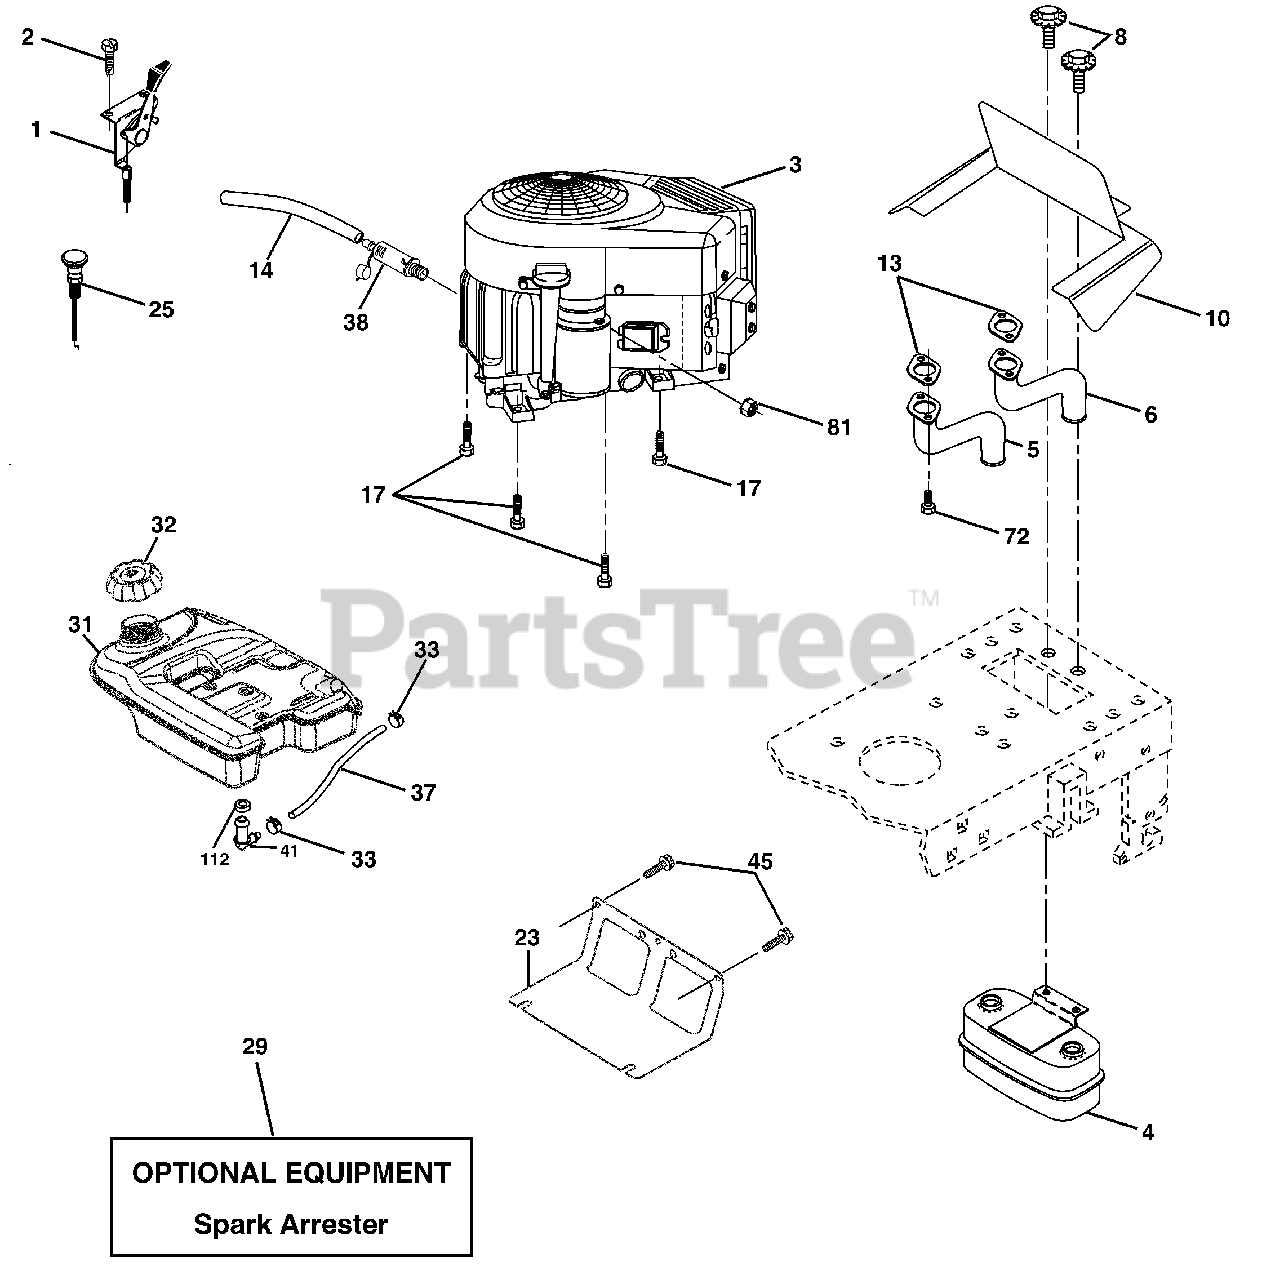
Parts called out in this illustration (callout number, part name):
1	Control Throttle
2	Screw Hw Hd Hi-Lo #13-16 x 3/4
4	Muffler Asm Twin Lo-Tone
5	Pipe Exhaust LH Intek
6	Pipe Exhaust RH Intek
8	Bolt 5/16-18 unc x 3/4 w/Sems
10	Shield Browning Intek II
13	Muffler Gasket
14	Tube Drain Oil Easy
17	Screw Thdrol 3/8-16 x 1-1/2
23	Shield Heat
25	Choke Control
29	Kit Spark Arrestor (Flat Scrn)
31	Tank Fuel 4.0 Rear
32	Cap Asm Fuel
33	Clamp Hose Black
37	Line Fuel
38	Plug Drain Oil
41	Stem Tank Fuel
45	Screw Hexwsh Thdr 3/8-16 x 3/4
72	Screw Socket Head 5/16-18 x 1
81	Nut Keps Hex 1/4-20 unc
112	Bushing
